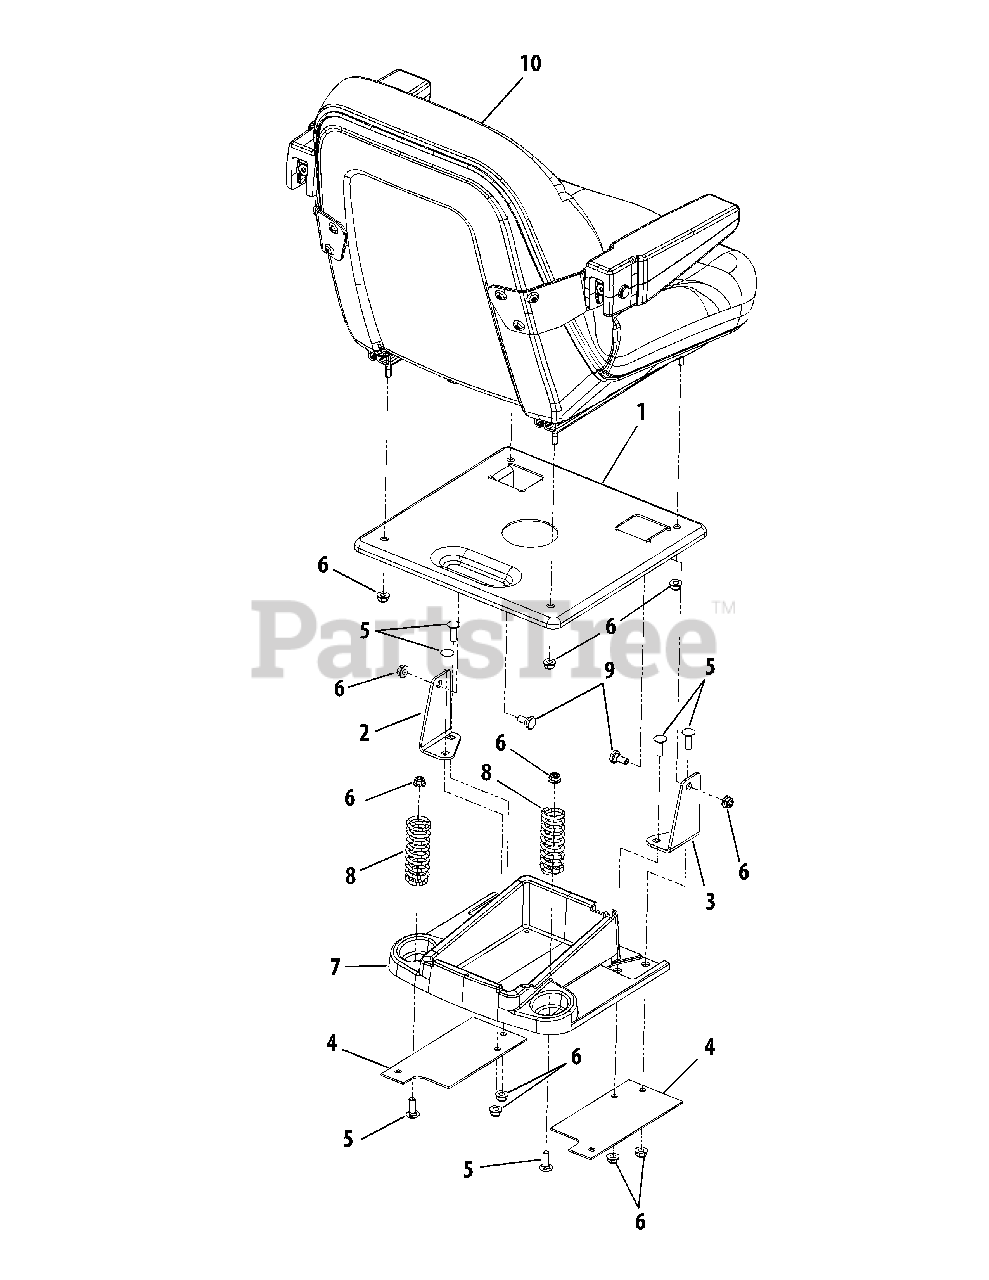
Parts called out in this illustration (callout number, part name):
2	Bracket, LH Seat Pivot
3	Bracket, RH Seat Pivot
4	Bracket, Fender Reinforcement
5	Bolt, Carriage, 5/16-18 x 1.0
6	Nut, Hx Insert Flnge Lck, 5/16-18 GrF
7	Tray, Tool
8	Spring, Compression
9	Bolt, Shoulder
10	Seat, High Back w/Arm Rests
